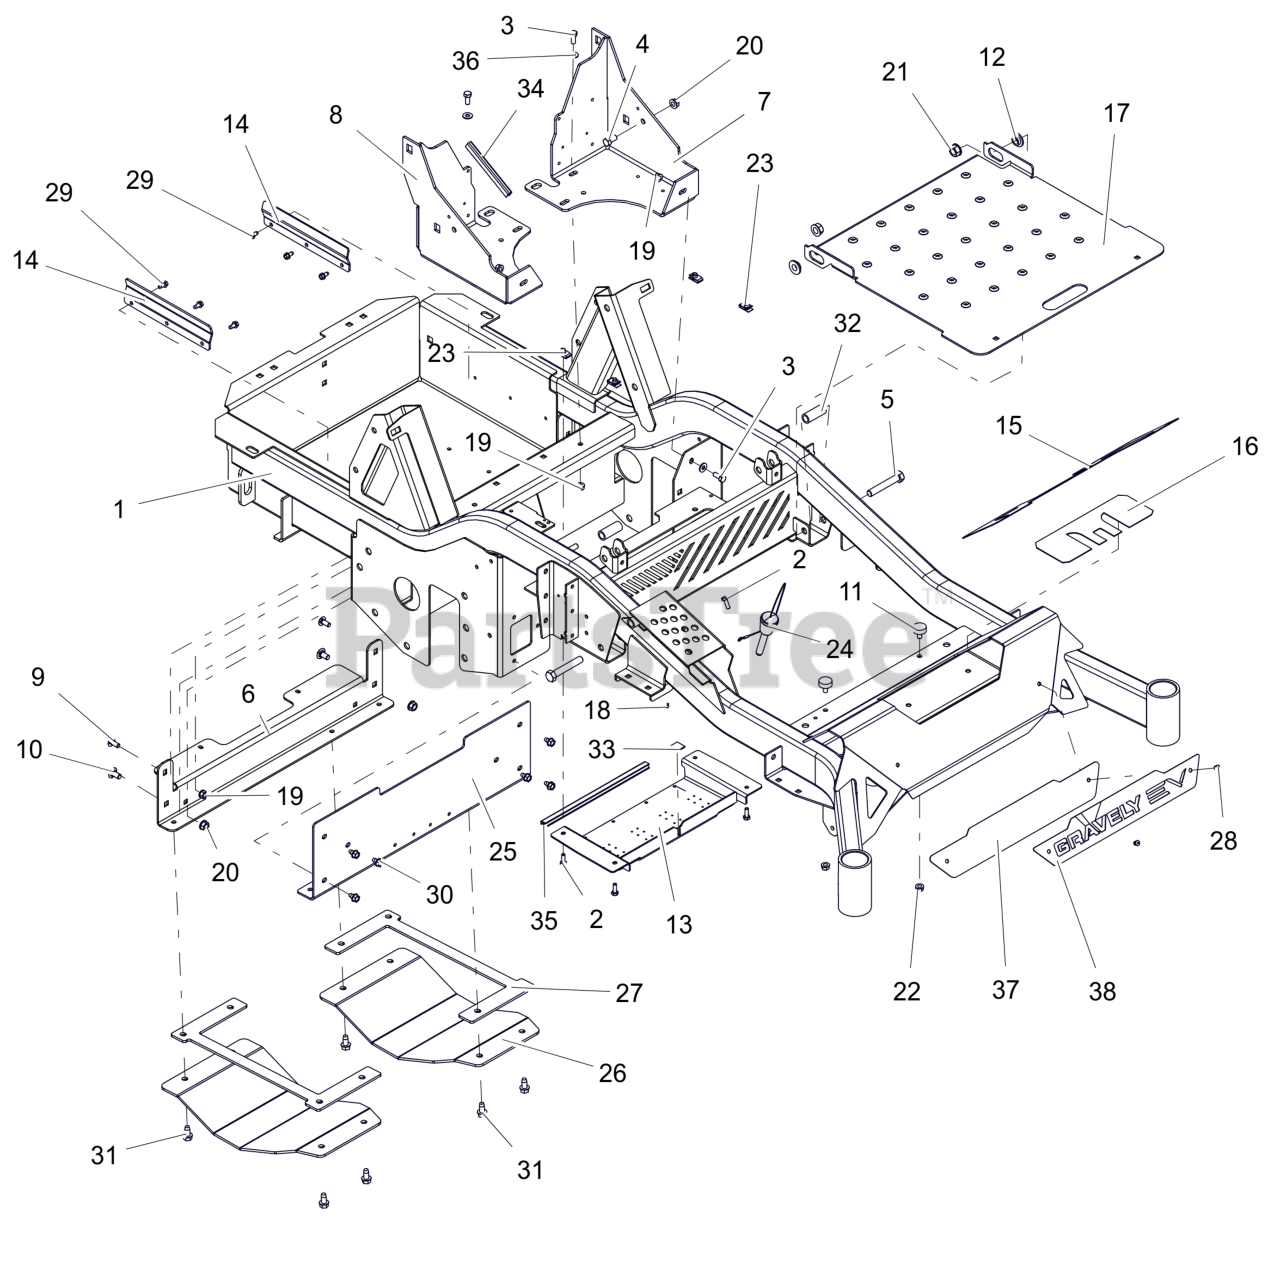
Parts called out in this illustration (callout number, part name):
1	KIT,EV FRAME(SM)W/DECALS-G
2	BLT, HEX .25-20X.75 G5 ZCC
3	BLT,HEX .31-18X.75 G5 ZCC
4	BLT,HEX .38-16X.75 G5 ZCC
5	BLT, HEX .50-13X3.00 G5 ZCC
6	BRKT, SKID PLATE MTG. (RED)
7	BRKT, SUPPORT ROPS -LH (RED)
8	BRKT, SUPPORT ROPS-RH (RED)
9	BLT, RHSSN.31-18X.750 G5 ZCC
10	BLT, RHSSN .38-16X.75 G5 ZCC
11	BUMPER, RUBBER
12	BSHG-FLG .515X.750X.310X1.120
13	COVER, BOTTOM ACCESS -OPEN (RED)
14	DEFLECTOR, BATTERY -EV (RED)
15	GRIP, FRONT
16	GRIP, TAPE FRONT
17	KIT,ACCESS PANEL W/DECALS-RED
18	NUT-LK-CTR-FLG .25-20 ZC120
19	NUT,LK-CTR-FLG .31-18 GF ZCC
20	NUT-LK-CTR-FLG .375-16 GF ZCC
21	NUT-LK-CTR-FLG .500-13 GG ZCC
22	NUT,SPNLK-FLG .31-18 G5 ZCC
23	NUT-RTNR .25-20X.56
24	PIN, MAGNETIC .50X2.50
25	PLATE, FRONT FRAME (RED)
26	PLATE, SKID (BLACK)
27	PLATE, SKID TENSION (BLACK)
28	RIVET, .1875 AL/AL .126-.250
29	SCR-TAP .25-20X.50 HWH ZCC
30	SCR,TAP .312-18X.50 HWH TR ZCC
31	SCR,TAP .375-16X.75 HWH TR ZCC
32	SPACER, .515X.75X1.83
34	STRIP, COWL
35	STRIP, COWL
36	WSHR, FLT .312X.734X.065 ZCC
37	PLATE, BACK - GRAVELY (BLACK)
38	PLATE, LOGO - GRAVELY EV (RED)
